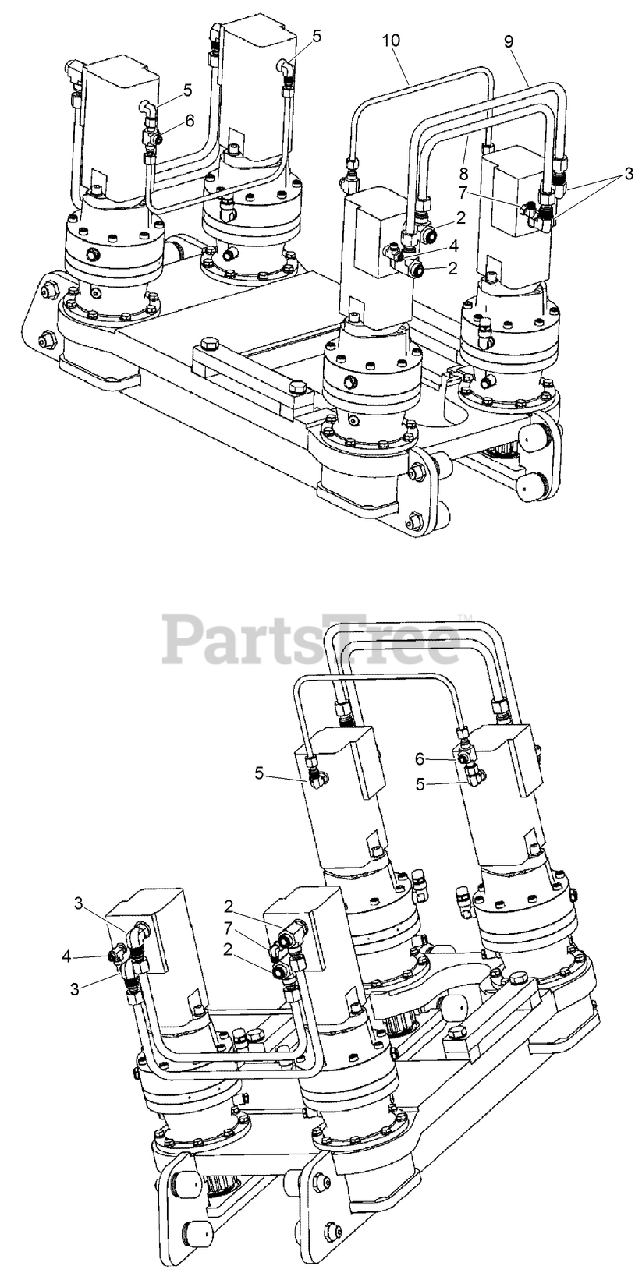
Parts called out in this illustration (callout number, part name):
2	CONNECTION - Run Tee, -10 ORFS / -10 ORB
3	CONNECTION - 90 Deg, -10 ORFS / -10 ORB
4	CONNECTION - Run Tee, -4 ORFS / -4 ORB
5	CONNECTION - 90 Deg, -6 ORFS / -6 ORB
6	CONNECTION - Run Tee, -6 ORFS / -6 ORFS
7	CONNECTION - 90 Deg, -4 ORFS / -4 ORB
8	TUBE-HYD, 5/8 IN (MOTOR TO MOTOR)
9	TUBE-HYD, 5/8 IN (MOTOR TO MOTOR)
10	TUBE-HYD, 3/8 IN (CASE DRAIN MTR TO MTR)
